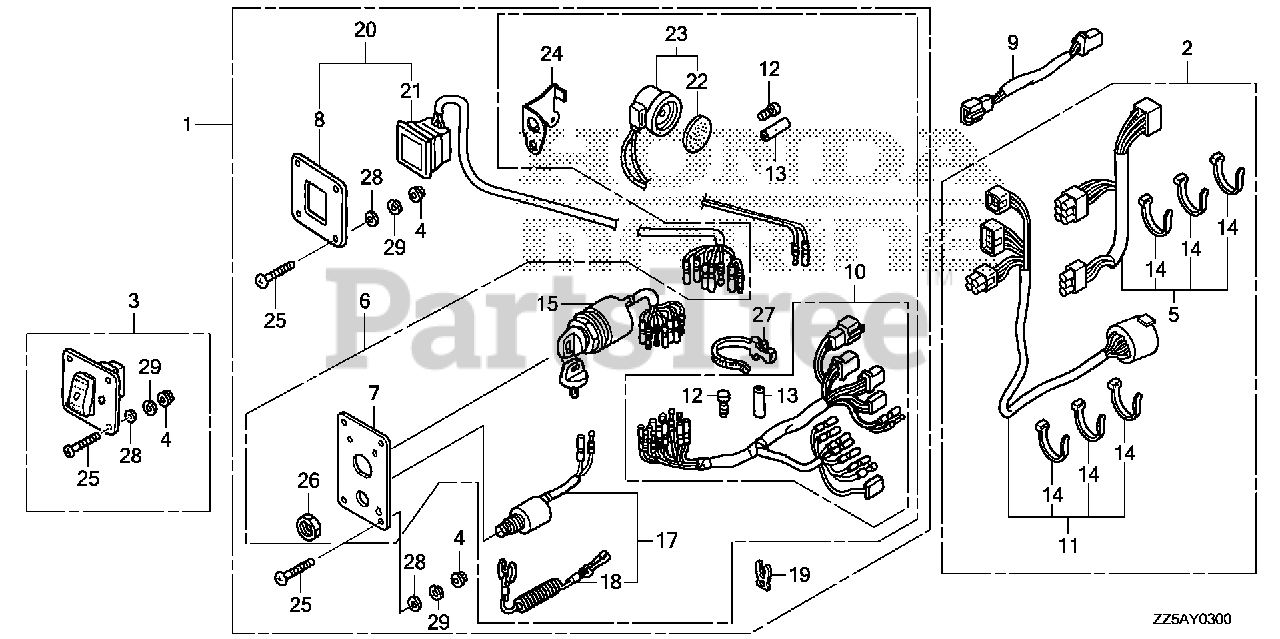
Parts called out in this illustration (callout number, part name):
1	PANEL KIT, SWITCH (4-LED) (B)
2	CABLE SET, PANEL INDICATOR (20FT)
2	CABLE SET, PANEL INDICATOR (25FT)
2	CABLE SET, PANEL INDICATOR (30FT)
3	SWITCH KIT, LIGHT
4	NUT, FLANGE (5MM)
5	WIRE ASSY., INDICATOR (20FT)
5	WIRE ASSY., INDICATOR (25FT)
5	WIRE ASSY., INDICATOR (30FT)
6	PANEL ASSY., SWITCH
7	PANEL, CONTROL
8	PANEL, CONTROL
10	HARNESS ASSY., SWITCH PANEL
11	CABLE ASSY., SWITCH PANEL (20FT) (NHK MEC)
11	CABLE ASSY., SWITCH PANEL (25FT) (NHK MEC)
11	CABLE ASSY., SWITCH PANEL (30FT) (NHK MEC)
12	PLUG, CONNECTOR (INNER)
13	PLUG, CONNECTOR (OUTER)
14	TIE, CABLE (2.4X92) (NATURAL)
15	SWITCH ASSY., COMBINATION
17	SWITCH ASSY., EMERGENCY STOP
18	WIRE, EMERGENCY
19	CLIP, EMERGENCY LOCK
20	PANEL ASSY., INDICATOR (4-LED)
21	LAMP ASSY., INDICATION (4-LED)
22	PLATE, TURN SIGNAL BUZZER
23	BUZZER, WARNING
24	BRACKET, BUZZER
25	SCREW, PAN (5X40)
26	NUT, HEX. (16MM)
27	BAND, WIRE HARNESS (150MM) (NATURAL)
28	WASHER, PLAIN (5MM)
29	WASHER, SPRING (5MM)
